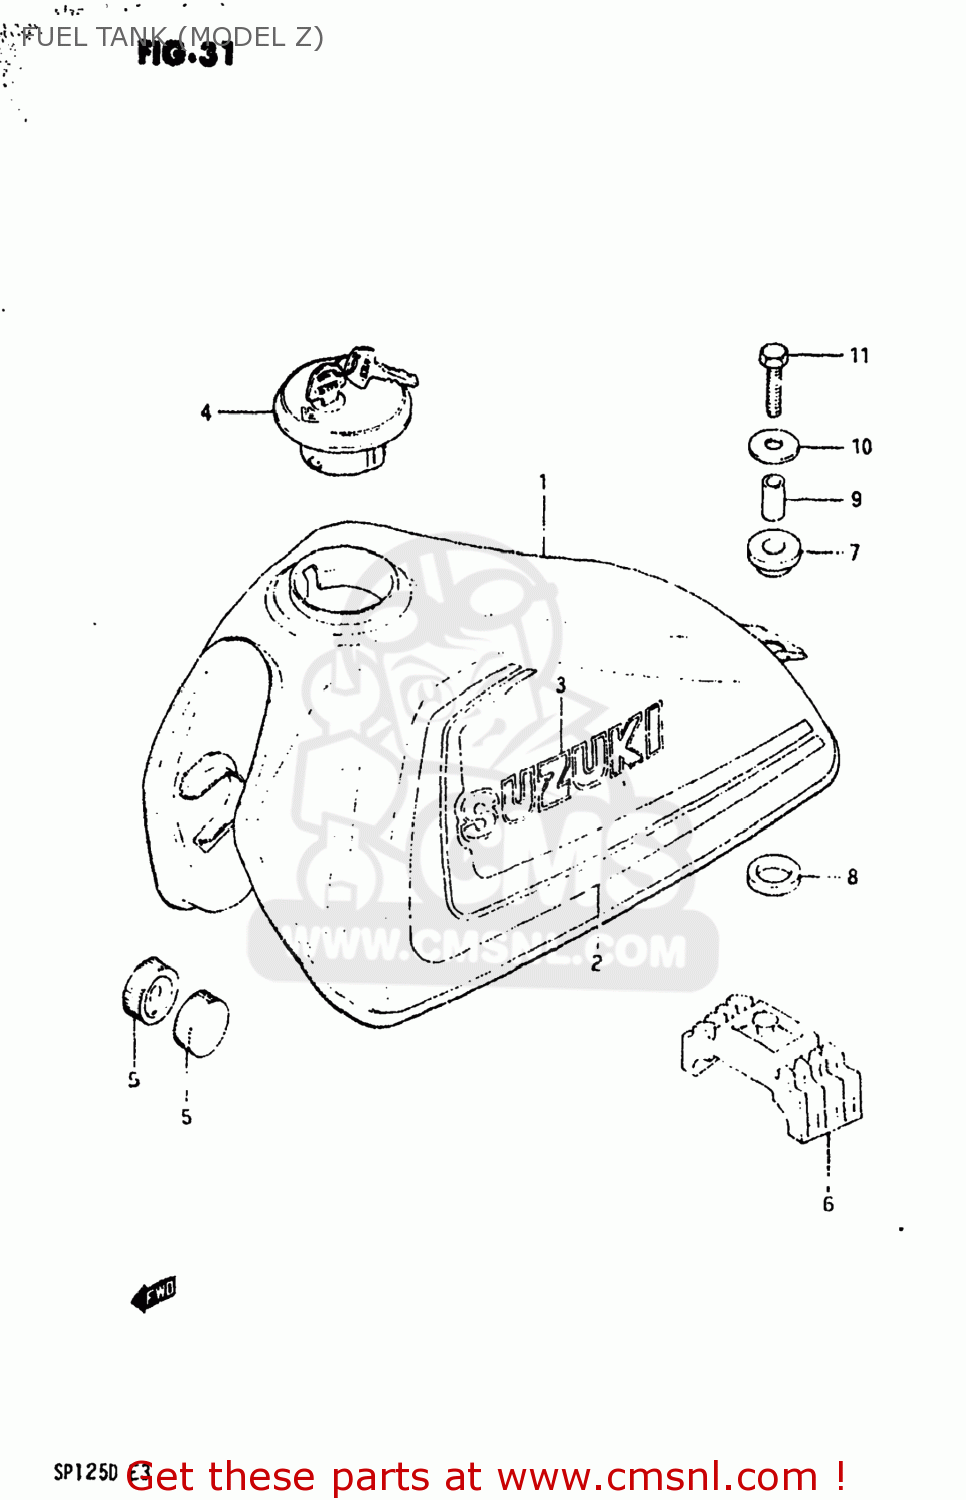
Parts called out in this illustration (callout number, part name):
1	TANK ASSEMBLY,FUEL
2	TAPE SET,FUEL TANK
3	EMBLEM(WHITE)
4	CAP SET,FUEL TANK
5	CUSHION
6	CUSHION,FUEL TANK
7	CUSHION
8	CUSHION
9	SPACER(8.5X12X19)
10	WASHER (8.5X29X1.6)
11	BOLT (8X30)
